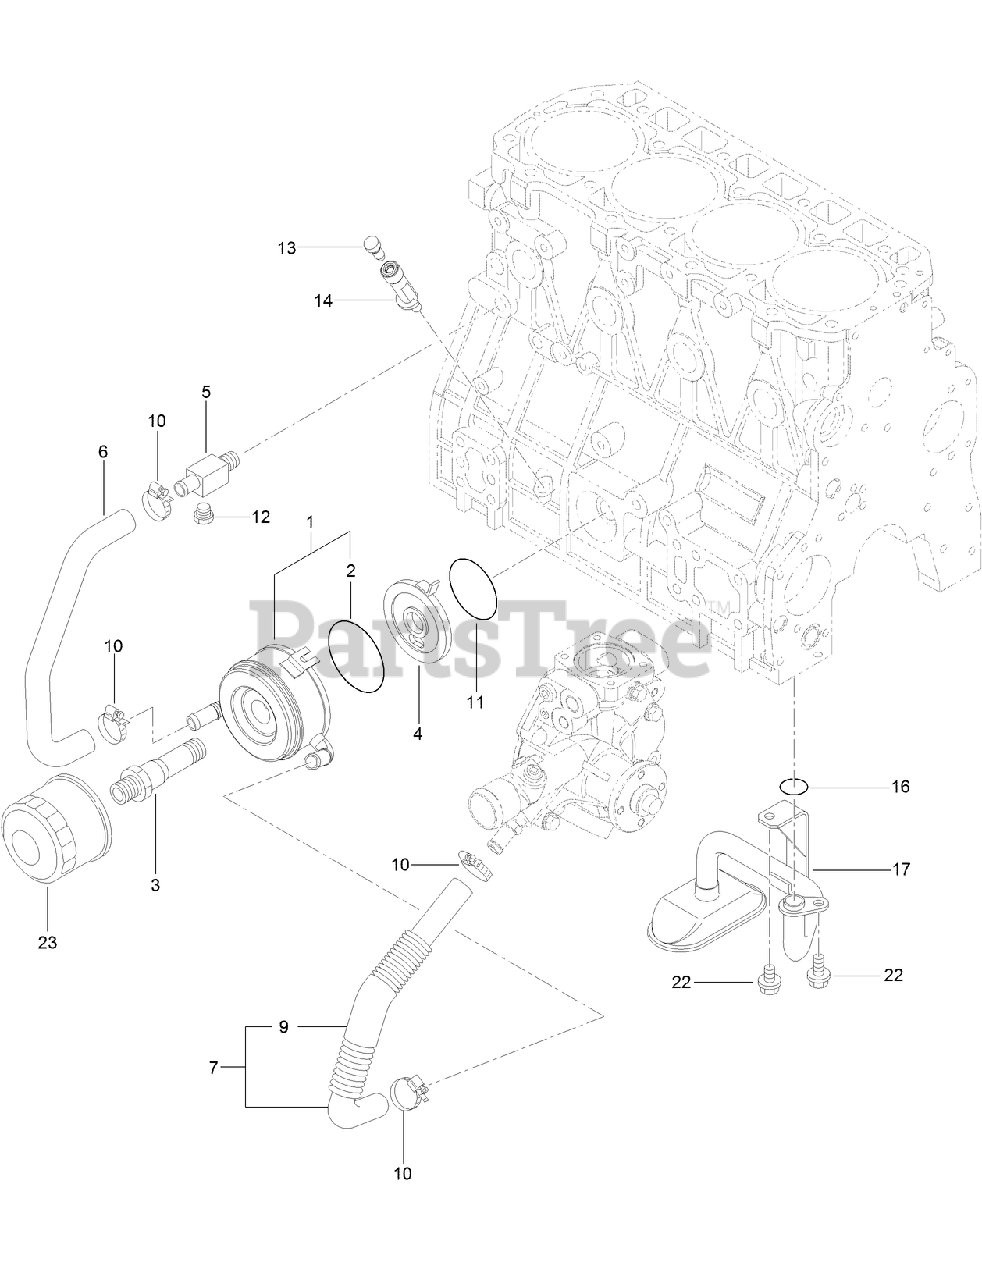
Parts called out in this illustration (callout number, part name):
1	COOLER ASM
2	O-RING
3	BOLT-COOLER
4	BRACKET-COOLER
6	PIPE-WATER
7	PIPE-WATER
9	TUBE-CORRUGATED
10	CLAMP-HOSE
11	O-RING
12	PLUG-DRAIN
13	PLUG-DIPSTICK
14	GUIDE-DIPSTICK
16	O-RING
17	OIL PICKUP TUBE ASM
23	FILTER-ENGINE
